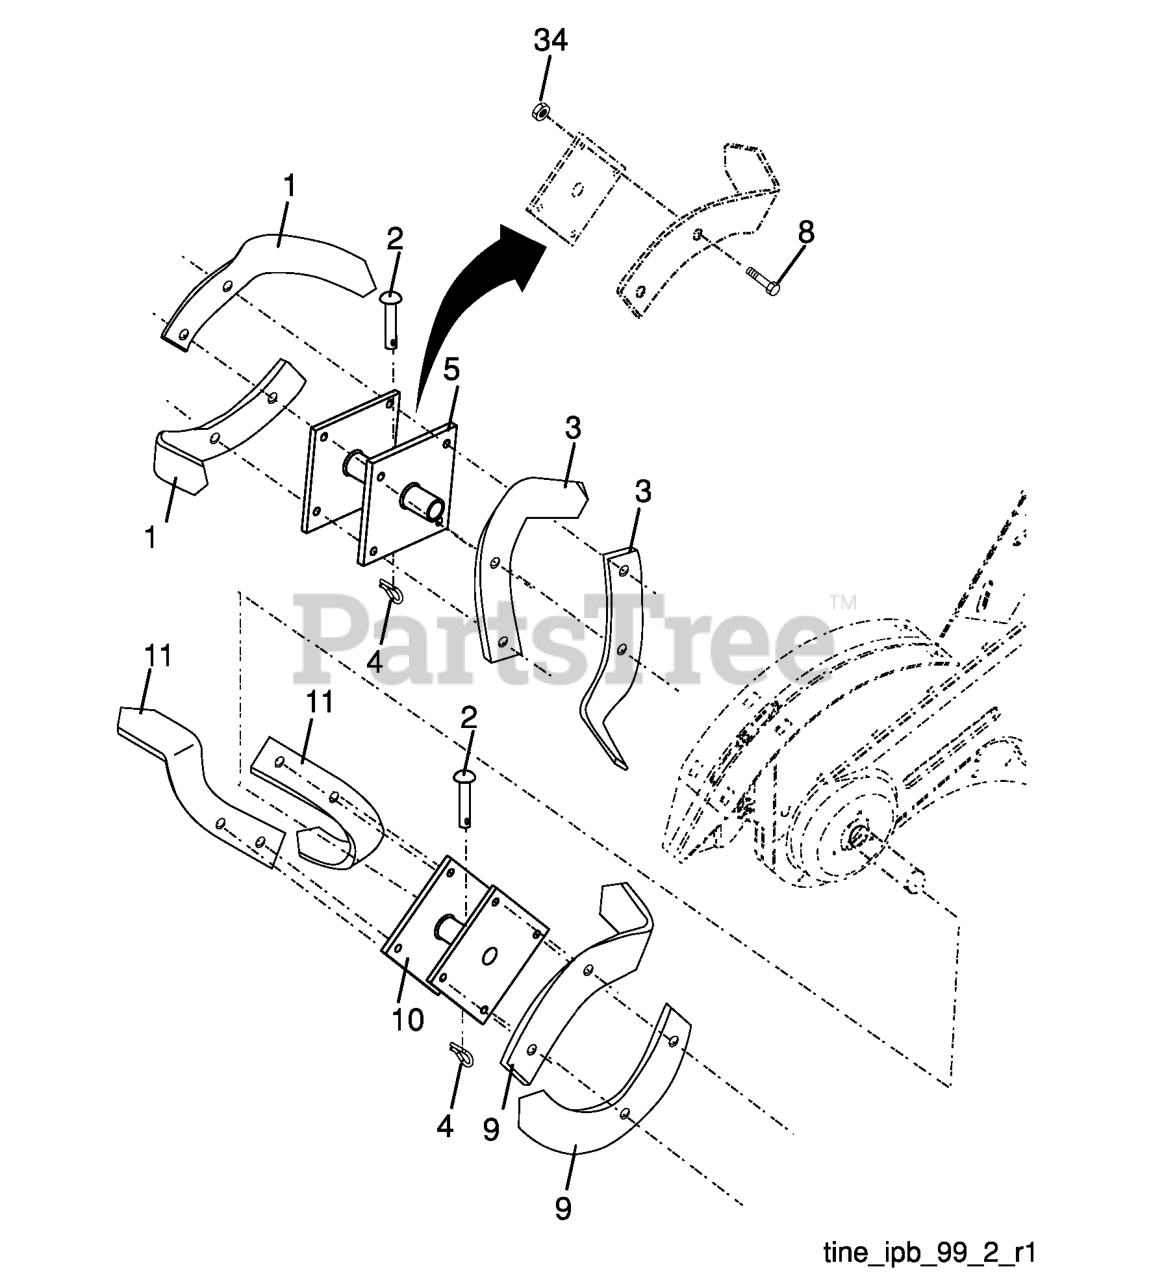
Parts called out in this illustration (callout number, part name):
1	TINE TI
2	PIN RETAINING SCREW
3	TINE.LH.12"(72L)
4	SPRING RETAINER
5	HUB.&.PLATE.LH.TILLER.BLACK
8	BOLT.HEX.001X20.37-24X1.ZINC
9	TINE TI
10	HUB.ASM.RH.14".BLACK.TILLER
11	TINE.RH.12"(72R)
34	NUT CROWNLOCK 3/8-24
